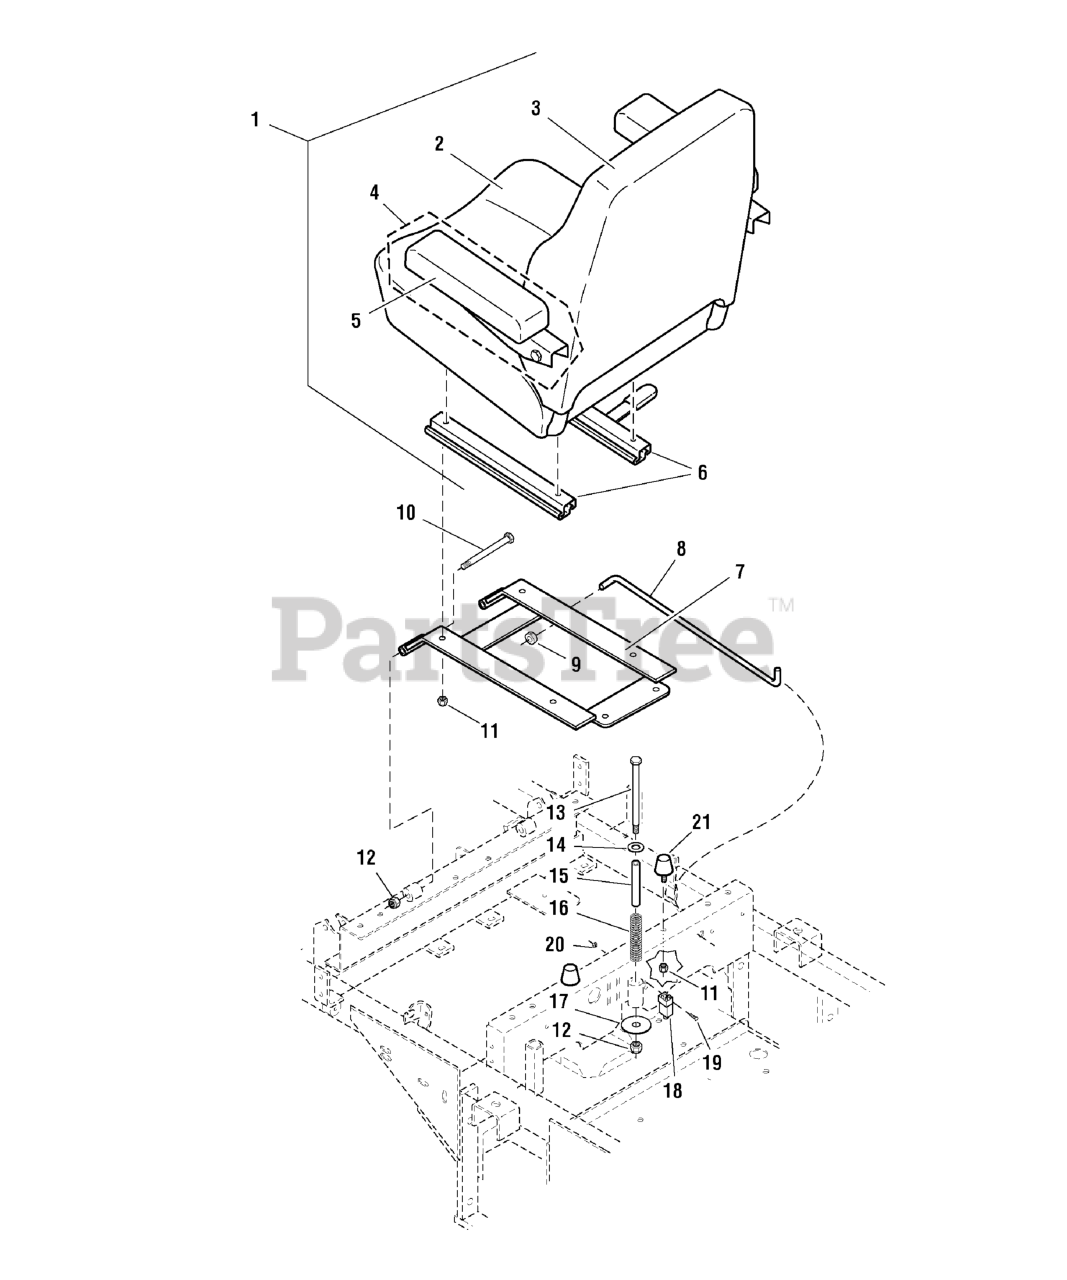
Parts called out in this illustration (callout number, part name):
1	SEAT, Deluxe, Gray, Complete
2	SEAT Bottom Cover
3	SEAT Back Cover
4	ARM REST SET
5	ARM REST PADS
6	SEAT ADJUSTER RAILS (set of 2)
7	WELD, SEAT MOUNT
8	SEAT STOP ROD
9	COLLAR, 5/16" Set
10	BOLT, 3/8-16 X 4" GD5 CZ
11	NUT, 5/16-18 Hex Nylon Lock
12	NUT, 3/8-16 HEX NYLON LOCK
13	BOLT, 3/8-16 X 6" GD5 CZ
14	WASHER, 3/8 SAE
15	SPACER, .38 X .50 X 5.06
16	SPRING, Compression
17	WASHER, 3/8 x 2
18	SWITCH (see electrical group)
19	SCREW, #10-24 X 1 RS, CZ
20	NUT, #10-24 Hex
21	RUBBER BUMPER
22	SPRING, EXTENSION, SEAT ADJUSTMENT (YEL OR BLK)
